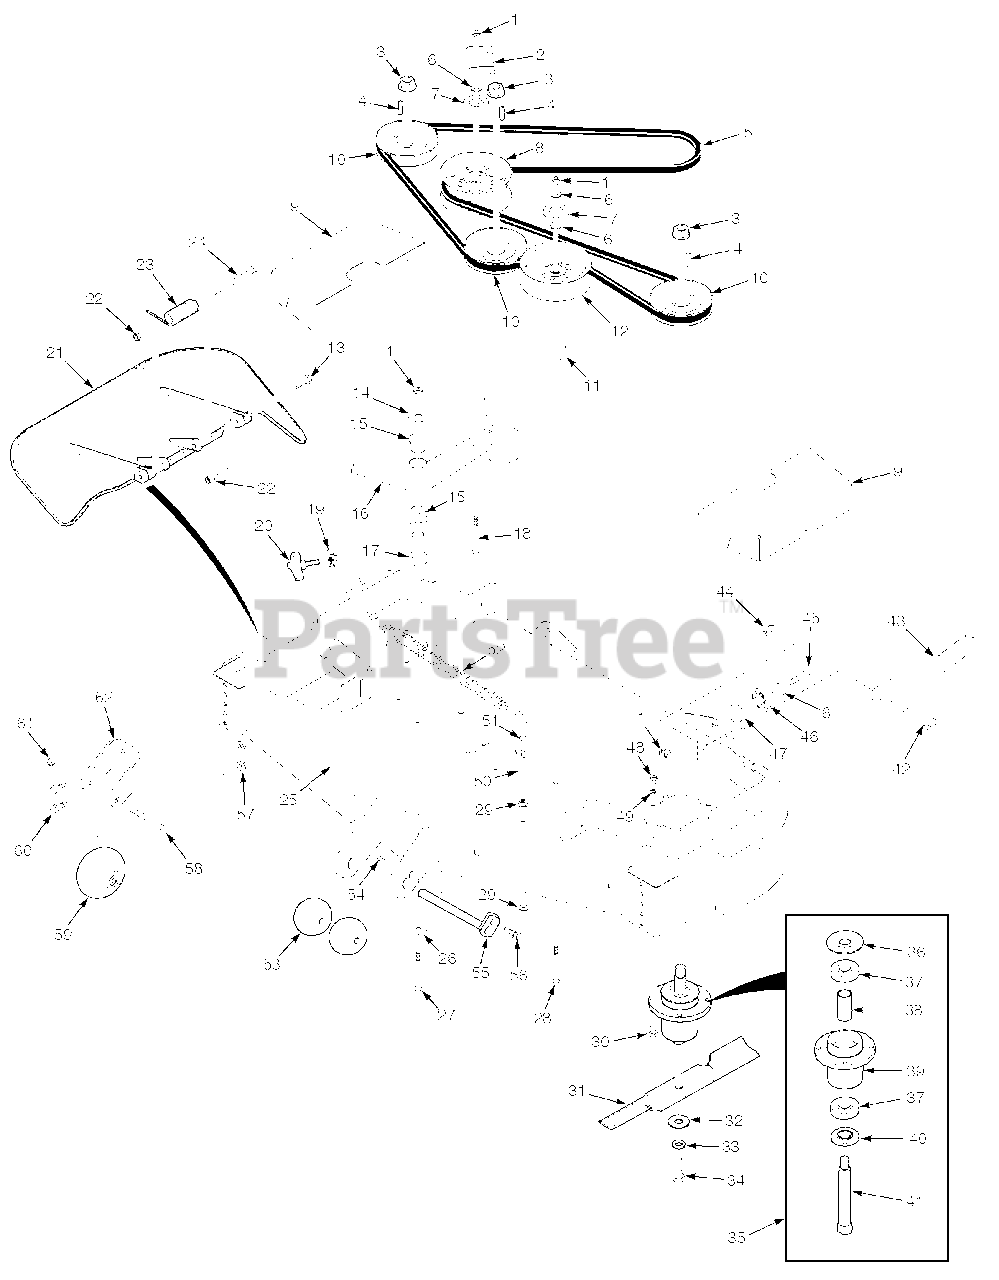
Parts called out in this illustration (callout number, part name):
1	Nut, Elastic Stop 3/8-16
2	Bracket, Belt Guide
3	Nut, 3/4-16 Spiral Lock
4	Key, 1/4 x 1/4 x 1-1/4"
5	Belt, Cutter Deck
6	Flatwasher, 3/8-.391 x .938 x .105
7	Dust Shield
8	Pulley, 5" Idler
9	Belt Cover
10	Pulley, 5.73" OD - 25mm Bore
11	Spacer
12	Pulley, 5" Idler
13	Bolt, Hex Head 5/16-18 x 1-3/4"
14	Flatwasher, 3/8-.406 x 1-1/2"
15	Bearing
16	Idler Arm
17	Pivot, Idler
18	Bolt, Hex Head 3/8-16 x 3-1/4"
19	U-Nut, 3/8-16
20	Knob w/Stud
21	Discharge Chute Assembly
22	Nut, Elastic Stop 5/16-18
23	Spring, Discharge Chute
24	Bolt, Hex Head 5/16-18 x 4-3/4"
25	Cutter Deck w/Decals, SMWZT-52
26	Flatwasher, 3/8-.406 x 2.25" x .188
27	Bolt, Hex Head 3/8-16 x 3-3/4"
28	Bolt, Hex Head 3/8-16 x 3-1/2"
29	Nut, Serrated Flange 3/8-16
30	Bolt, Hex Head 5/16-18 x 1-1/2"
31	Cutter Blade, 18"
32	Flatwasher, 5/8-.688 x 1.75 x .134 HD
33	Lockwasher, 1/2 Spring
34	Bolt, Hex Head 5/8-11 x 1-1/2"
35	Spindle Assembly
36	Debris Shield
37	Bearing
38	Spacer
39	Spindle Housing Assembly
40	Protector, Bearing
41	Shaft, Spindle
42	Bolt, Shoulder 1/2 x 3/8-16 x 2-3/4"
43	Pusharm
44	Nut, Elastic Flange 3/8-16
45	Bolt, Hex Head 3/8-16 x 1-3/4"
46	Bearing
47	Spacer, Bearing
48	Nut, Elastic Stop 5/16-18
49	Lockwasher, 5/16 Spring
50	Spacer
51	Bolt, Hex Head 3/8-16 x 1-1/2
52	Spring, Idler
53	Wheel, Anti-Scalp
54	Nut, Serrated Flange 5/16-18
55	Shaft Weldment
56	Bolt, Hex Head 5/16-18 x 1"
57	Nut, Serrated Flange 3/8-16
58	Bolt, Carriage 3/8-16 x 4"
59	Wheel, Anti-Scalp
60	Bolt, Hex Head 3/8-16 x 1" Ser. Flg.
61	Nut, Center Lock 3/8-16
62	Bracket, Anti-Scalp
